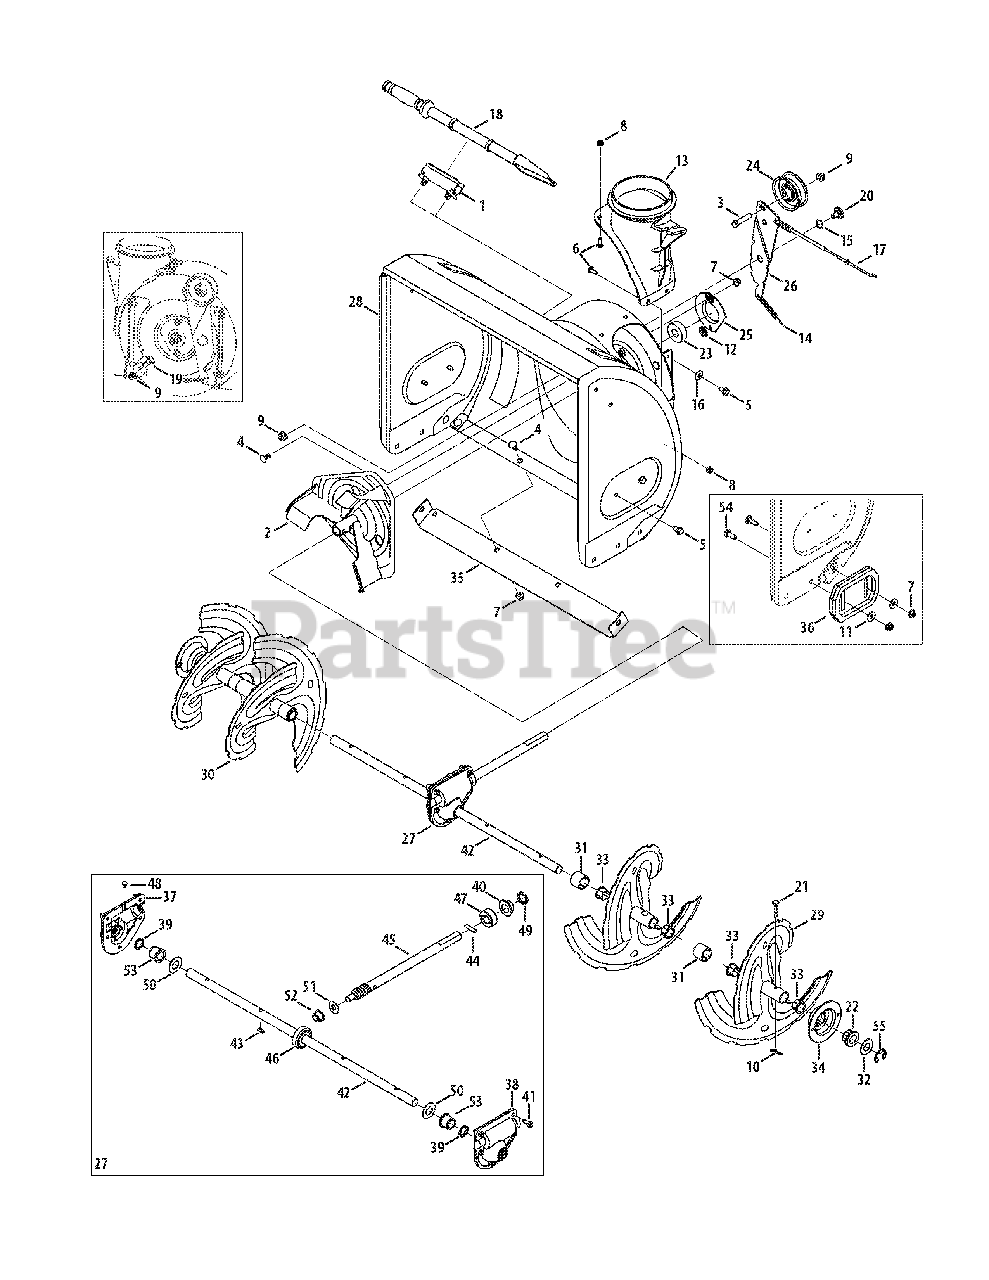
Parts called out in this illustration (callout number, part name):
1	Snow Removal Tool Mount
2	Impeller Assembly, 12" Dia.
3	Hex Screw, 3/8-16, 1.75, Gr5
4	Bolt, Carriage, 5/16-18, .750 Gr1
5	Screw, 5/16-18, 0.750
6	Screw, Carriage, 1/4-20, .750, Gr5
7	Nut, Flange Lock, 5/16-18, Nylon
8	Nut, Flange Lock, 1/4-20, Nylon
9	Nut, Flange Lock, 3/8-16, Nylon
10	Cotter Pin, Bow-tie
11	Washer, Flat, .349 x .879 x .063
12	Nut, Push-on, .25 Dia
13	Chute, Adapter 5" Dia
14	Spring, Extension, .38 OD x 4.59
15	Washer, Wave, .625 x .885 x .015
16	Washer, Bell, .340 x .872 x .060
17	Clutch Cable, Auger, 47.23"
18	Snow Removal Tool
19	Screw, Shoulder, .498 x .34, 3/8-16
20	Screw, Shoulder, .625 x .17, 3/8-16
21	Shear Pin, .25 x 1.50
22	Bearing, Hex Flange x .75 ID
23	Bearing, Ball, .75 ID x 1.85 OD
24	Flat Pulley, Idler, 2.75 OD
25	Housing, Bearing, 1.85 ID
26	Bracket, Auger Idler w/ Brake
27	Gearbox Assembly, Auger, 24"
28	Housing Assembly, Auger 24"
29	Spiral Assembly, LH
30	Spiral Assembly, RH
31	Spacer, 1.25 OD x .75 ID x 1.00
32	Washer, Flat, .76 x 1.49 x .06
33	Bushing, Flange, .80 ID x .91 OD
34	Housing, 1" Hex Bearing
35	Shave Plate, 2.25 x 23.66
36	Slide Shoe, Standard Polymer
36	Skid Shoe Kit, Standard Polymer Reversible
37	Housing, Auger, RH Reduced
38	Housing, Auger, LH Reduced
39	Seal, Oil, .750 x 1.00 x .125
40	Bearing, Flange, .75 x 1.0 x .59
41	Screw, Self-tapping, 1/4-20, 0.750
42	Axle, Auger, 24"
43	Key, Hi-pro 3/16 x 5/8
44	Pin, Dowel, .25 OD x 1.2
45	Shaft, Worm .75 OD
46	Gear, Worm 20T
47	Collar, Thrust
48	Plug, 1/4 x .437
49	Seal, Oil, .75 x 1 x .131
50	Washer, Flat, .760 ID x 1.5 OD
51	Washer, Flat, .51 x 1.12
52	Bearing, Flange, .75 x 1.0 x .925
53	Bearing, Flange, .75 x 1.00 x .975
54	Screw, Carriage, 5/16-18 x 1.00
55	E-Ring
